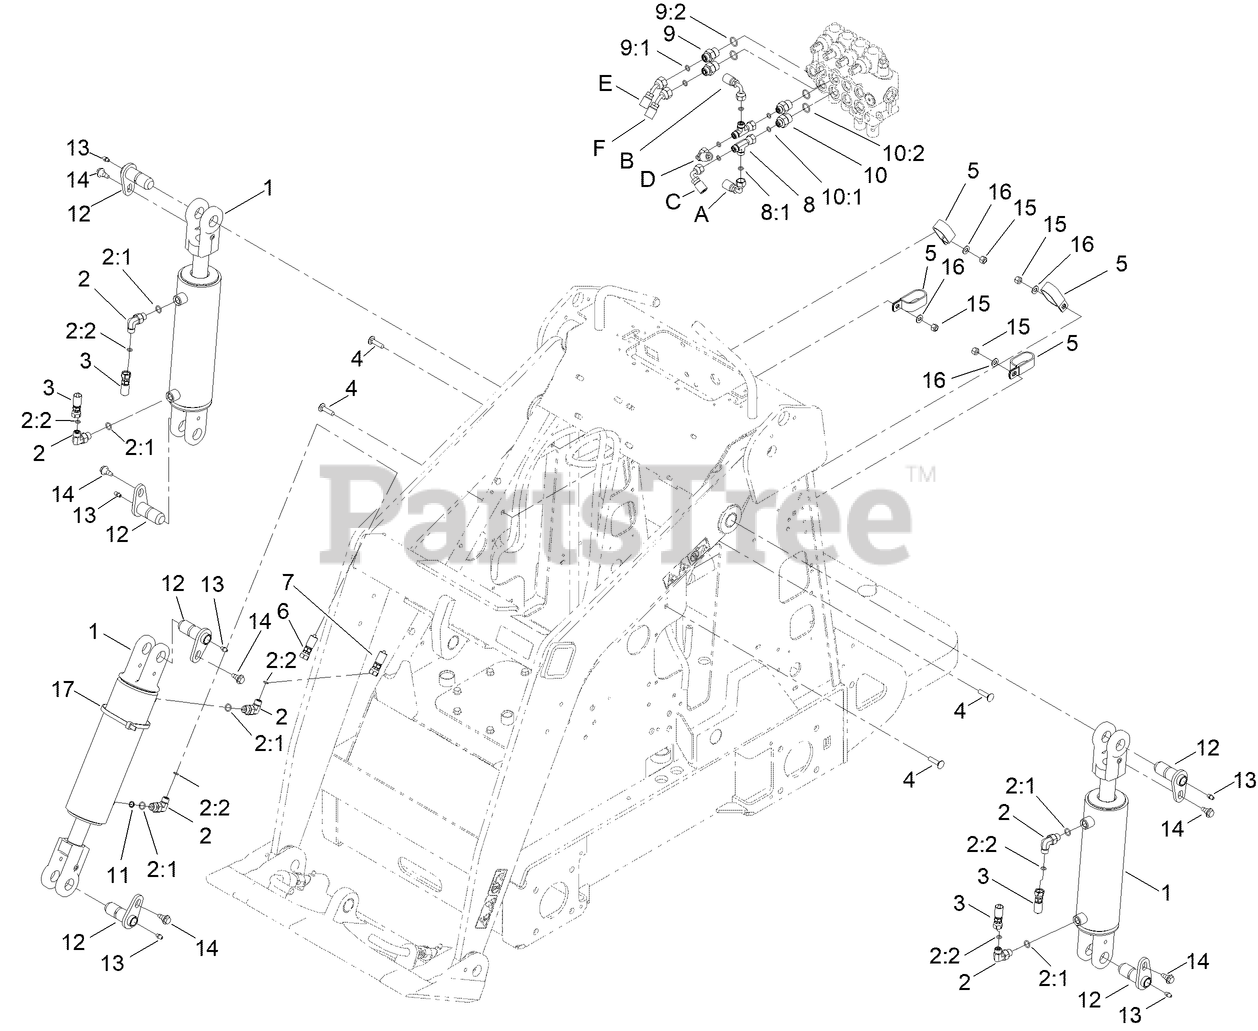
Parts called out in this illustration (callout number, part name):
1	CYLINDER-HYD
2	FITTING-ELBOW, 90 DEG
2:1	O-RING
2:2	O-RING
3	HOSE-HYD
4	SCREW-CARR
5	CLAMP-R, DOUBLE
6	HOSE-HYD
7	HOSE-HYD
8	FITTING-HYD
8:1	O-RING
9	FITTING-STRAIGHT
9:1	O-RING
9:2	O-RING
10	FITTING-STR
10:1	O-RING
10:2	O-RING
11	ORIFICE-PORT INSERT, ONE WAY
12	PIN-PIVOT
13	FITTING-GREASE
14	BOLT-SHOULDER
15	NUT-LOCK, NI
16	WASHER-PLAIN
17	TIE-CABLE
